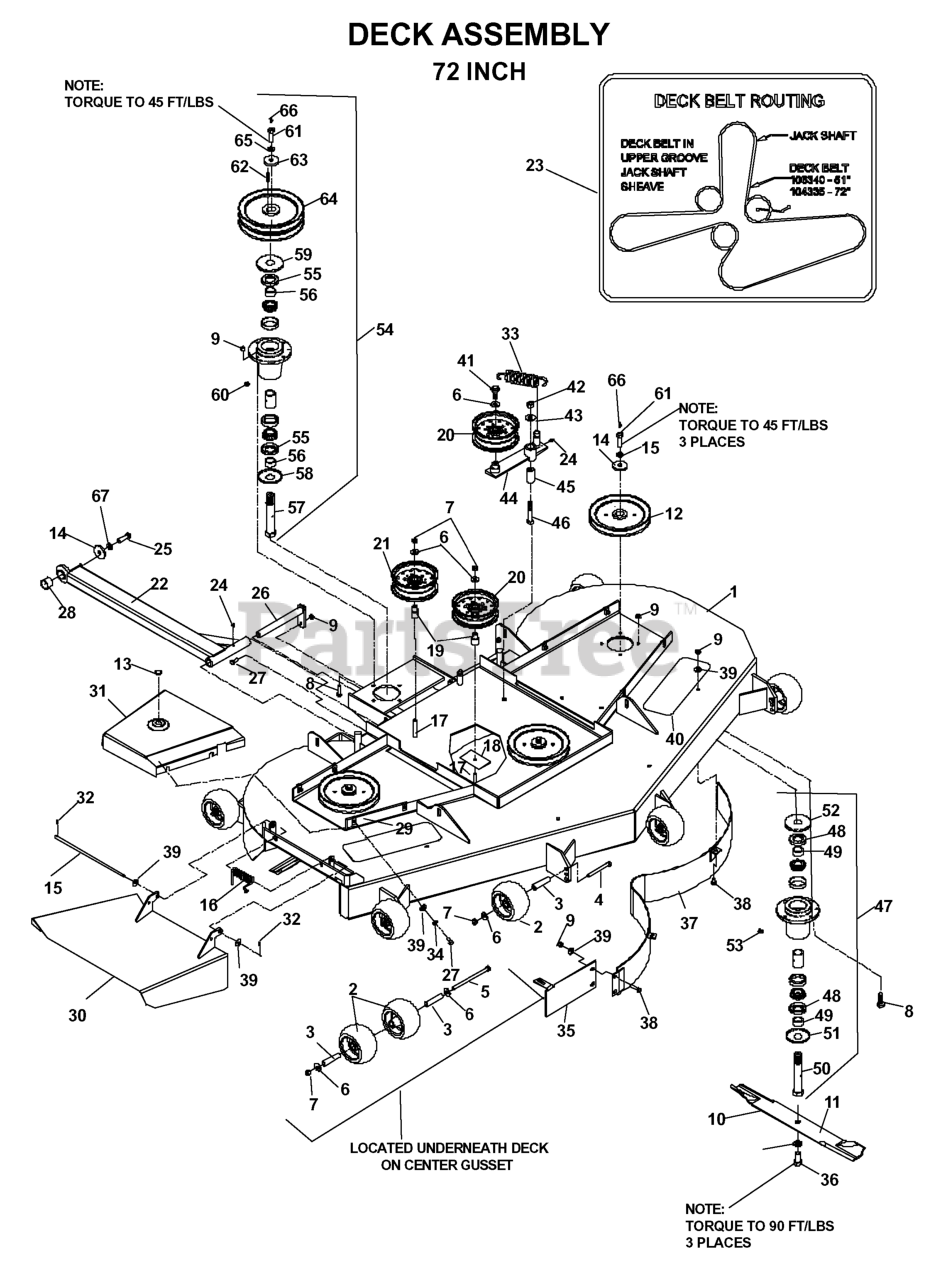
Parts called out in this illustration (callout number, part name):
1	DECK W/DECALS 72" HUS
2	ANTI-SCALP ROLLER
4	HCS 3/8C X 3 1/2
5	BOLT 3/8 X 6" GRD 8
6	WASHER 3/8 FLAT
7	NUT 3/8C CENTERBLOCK
8	HCS 5/16C X 1
9	NUT 5/16C CENTERLOCK
10	BLADE OEM - 25"
11	BELLEVILLE SPRING WASHER
12	RP PULLEY - 72"
13	PLUG, BUTTON HOLE
14	SPINDLE WASHER
15	PIN 5/16 X 11-1/2 PIVOT SPEC
16	SPRING, TORTION
17	HCS 3/8C X 2 1/2
18	SUPPORT PLATE
19	IDLER BUSHING
20	IDLER PULLEY
21	IDLER PULLEY (TALL)
22	STRUT WELDMT - R.H
23	BELT, DECK
24	ZERK
25	HCS 7/16F X 1 1/2
26	PIN WELDMENT
27	HCS 5/16C X 3/4
28	SPACER, STRUT
29	U-CLIP 5/16-18 NUT RETAINER
30	DISCHARGE CHUTE
31	RT 72 SHIELD CE ORANGE
32	COTTER PIN
33	DECK SPRING
34	WASHER.LOCK.HVY.HLCL.SPR.5/16
35	BAFFLE/CENTER-FLAT BLK
36	HEX SCREW-5/8F X 2 GR8
37	BAFFLE/CENTER-CURVED
38	CARRIAGE BOLT 5/16C X 5/8"
39	WASHER 5/16 FLAT
40	ANTI-SKID PAD
41	4CS 3/8C X 1 SERRATED HEAD
42	NUT 1/2-13 HEX NYLOC ZD
43	WASHER 1/2 FLAT
45	PIVOT BUSHING
46	HCS 1/2C X 3 1/4
47	SPINDLE
48	SHAFT SEAL
50	SPLINED SHAFT - 72"
51	BOTTOM DUST CAP
52	TOP DUST CAP
53	PLUG-VENTED
54	JACKSHAFT ASSY LOWER
55	SHAFT SEAL
57	JACKSHAFT SPINDLE
58	BOTTOM DUST CAP
59	TOP DUST CAP
60	PLUG-VENTED
61	HCS 7/16C X 1 1/2
62	KEY 1/4 SQ X 1 1/8
63	SPINDLE WASHER
64	SHEAVE WSL
65	WASHER 7/16 LOCK
66	ZERK
67	WASHER 7/16 LOCK
539107751	STRUT WELDMT, L.H.
539108934	LT 72 SHIELD CE ORANGE
